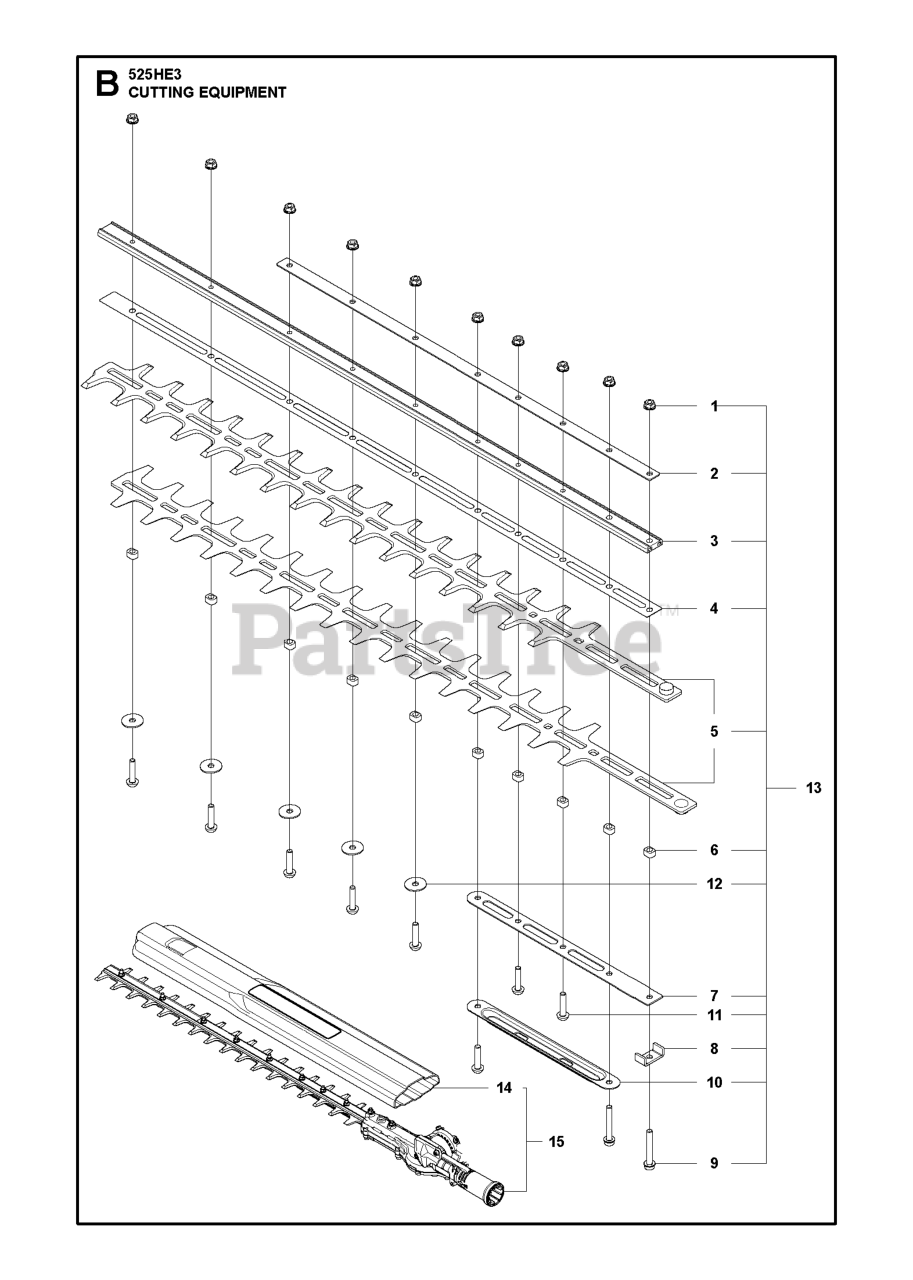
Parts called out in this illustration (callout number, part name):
1	NUT HEXAGON LOCK WITH FLANGE M
2	BAR PLATE UPPER
3	GUIDE BAR HD/HS60
4	WEAR PLATE
5	BLADE KIT HD60
6	SPACER CUTTING DECK
7	BAR PLATE LOWER
10	BAR PLATE LOWER
11	SCREW HEXALOBULAR SOCKET BUTTO
12	WASHER PLAIN 5.5X19X1.2 ST TBO
13	CUTTING DECK KIT HD60
14	TRANSPORT GUARD HUSQVARNA GRE
15	CUTTING HEADS
